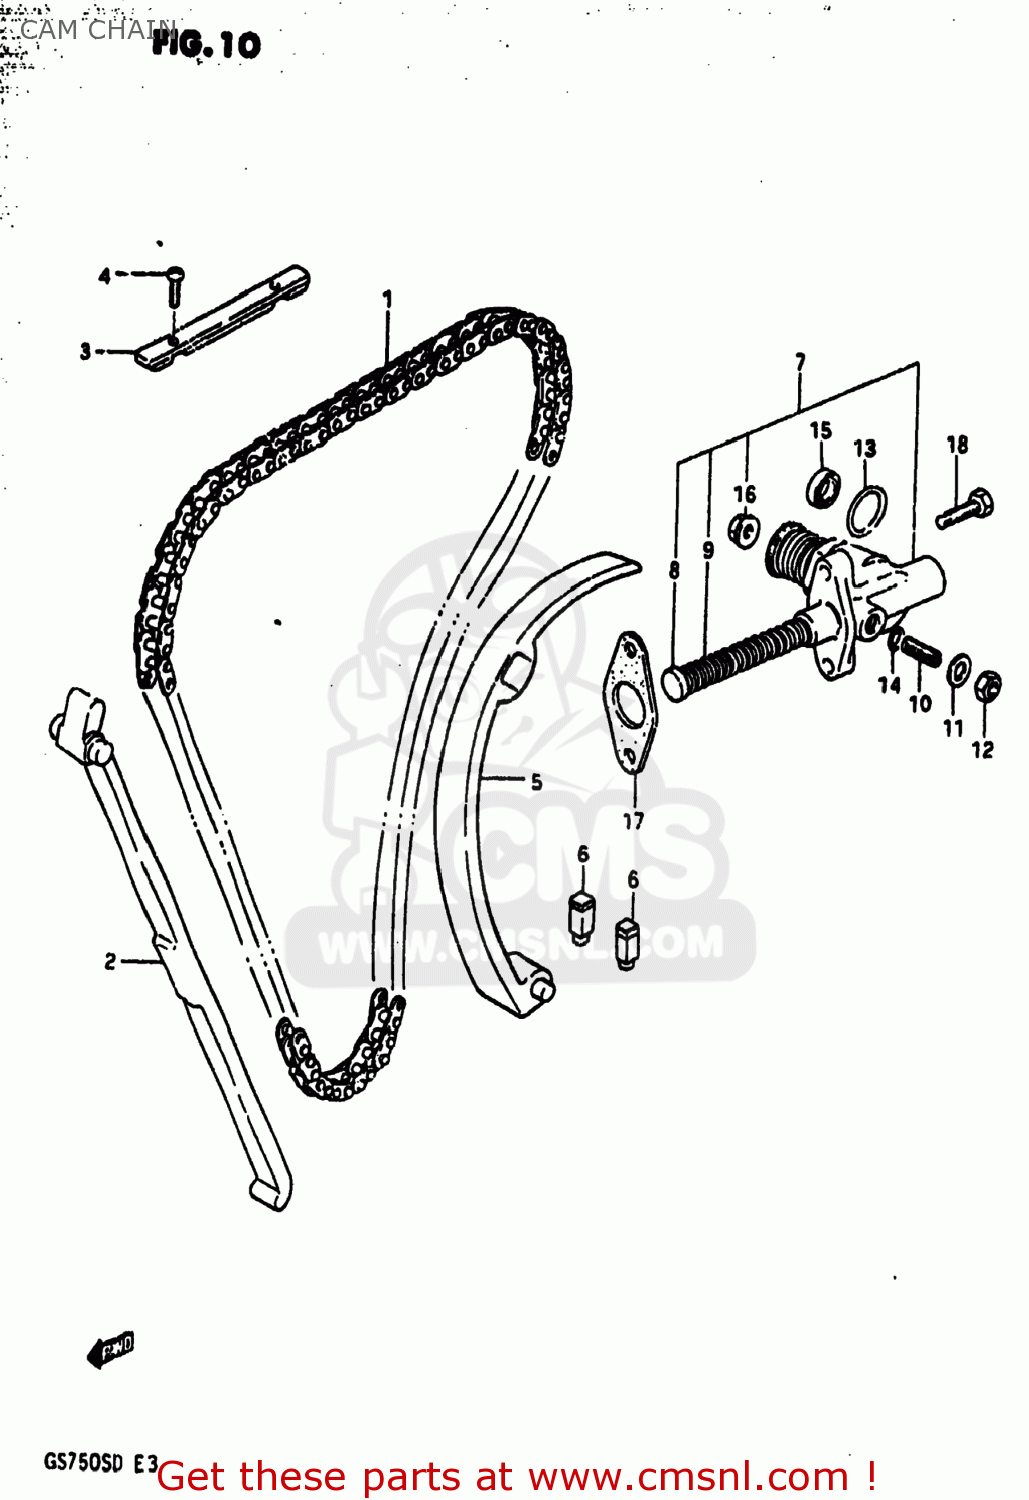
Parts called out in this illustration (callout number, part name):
1	CHAIN,CAMSHAFT DRIVE
2	GUIDE,CAM CHAIN NO.1
3	GUIDE,CAM CHAIN NO.3
4	SCREW
5	TENSIONER,CAM CHAIN
6	CUSHION,CAM CHAIN TENSIONER
7	ADJUSTER ASSEMBLY,TENSIONER
8	ROD,PUSH
9	SPRING
10	SCREW,TENSIONER ADJUST
11	WASHER,8.5X16X
12	NUT
13	O-RING
14	O-RING
15	OIL SEAL
16	NUT
17	GASKET,TENSIONER ADJUSTER (MCA)
18	SCREW
